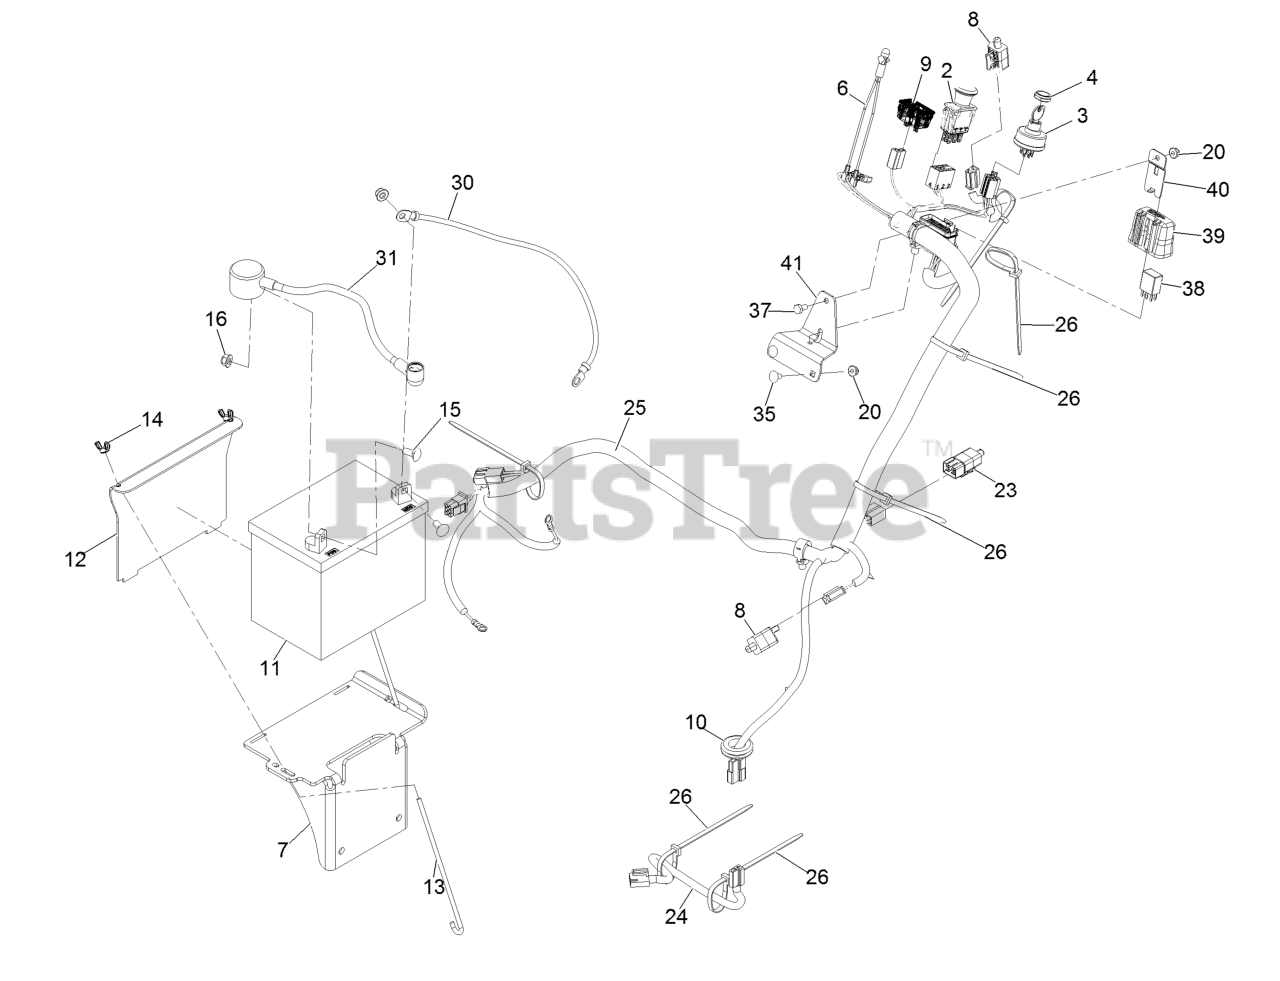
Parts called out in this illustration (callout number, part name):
2	Switch-PTO
3	Switch, Key Start
4	Nut-Ignition
6	Indicator-Red LED
7	Weld, Battery Mount
9	Hour Meter
10	Grommet
11	Battery (300 CCA, Wet)
12	Bracket, Battery Hold Down
13	Bolt-Holddown
14	Wingnut-Nyloc 1/4-20
15	Bolt-Carriage 5/16-18 X 3/4
16	Nut-Nyloc 5/16-18 Flg
20	Nut-Nyloc 1/4-20 Flg
23	Switch, 2 Pole
24	Harness-Clutch Pigtail
25	Harness-Wiring
26	Tie-Cable 7 15/16 (Large)
30	Cable-Battery, Negative
31	Cable, Battery +
35	Bolt-Carriage 1/4-20 X 1/2
37	Screw-HH 1/4-20 X 1/2
38	Relay-Micro 280, Spdt
39	Cover-Block, Fuse
40	Clip-Mounting
41	Bracket-Mounting,Fuseblock
